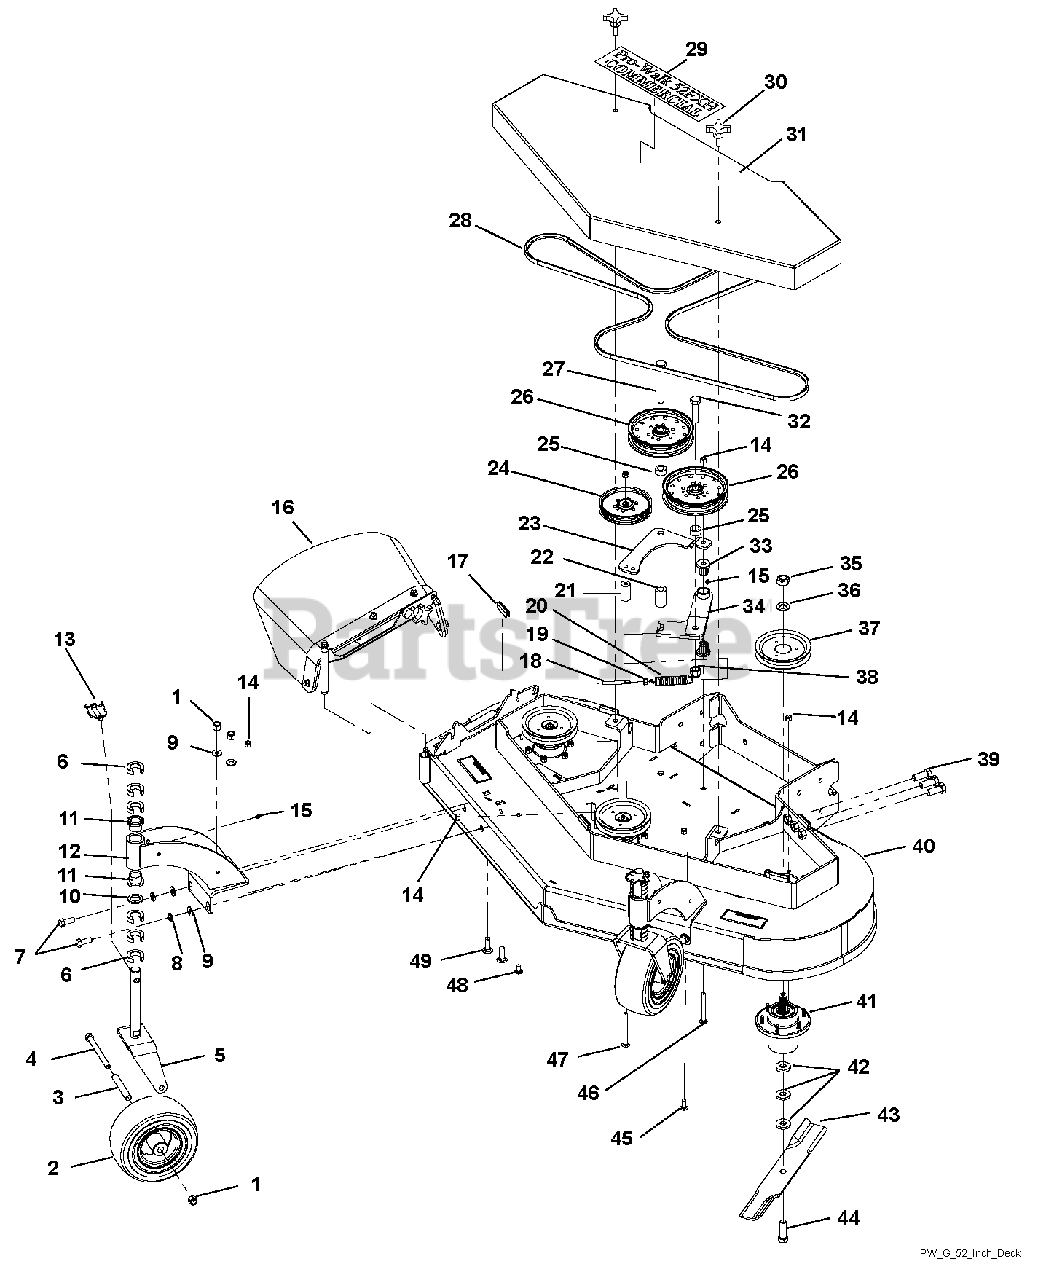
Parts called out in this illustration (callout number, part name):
1	Locknut, .50-13 Nyloc
2	Assembly, Wheel and Tire 9 x 3.5
3	Tube, Caster Axle
4	Bolt, .50-13 x 5.50 Hex Grade 5
5	Weldment, Caster Yoke w/Gravely Paint
6	C-Spacer, 1.00 x 1.77 x .500
7	Bolt, .50-13 x 1.25 Hex 5
8	Washer, Lock .50 x .125 Regular
9	Washer, Flat .50 x 1.25 x .083
10	Bushing, 1.03 x 1.50 x .179
11	Bearing, Flange 1.00 x 1.25 x 1.00
12	Weldment, Strut Front FXWLK w/Gravely Paint
13	Pin, LNC .438 x 2.00
14	Locknut, .38-16 Nyloc
15	Fitting, .25-28 STRGT Grease Zerk
16	Discharge Shield Assembly
17	Trim, 1/4" Trim-LOK
18	Rod, Threaded Adjustment
19	Nut, .375-16 Spring Lock Flanged
20	Spring, Ext .875 x .125 x 4.25
22	Bushing, .688 x 1.13 x 1.89
23	Strap, Idler 52 FXWLK
24	Pulley, Flat 5.00 x .375 w/Bearing
25	Bushing, .688 x 1.13 x .55
26	Pulley, Flat 6.00 x .635 w/Bearing
27	Bolt, .62-11 x 4.50 Hex Grade 5
28	Belt, HB 124.0 Elbow AMD
29	Decal, Pro-Walk Commercial 52 FXH
30	Knob, .375 x 1.25-4 Prong
31	Weldment, 52" Belt Shield Gravely
32	Bolt, Hex .62-11 x 2.50 Grade 5
33	Bearing, Flange M10 x M25 x M27 Fluted
34	Weldment, Idler Arm
35	Locknut, .75-16 Crown
36	Washer, .75 x 1.313 x .113
37	Pulley, Spline Spindle Offset
38	Nut, Lock, Nylon .625-11
39	Bolt, .625-11 x 1.50 Hex Grade 8
40	Assembly, Deck 52 Gravely w/Decals
41	Assembly, Spindle Housing
42	Washer, Blade
43	Blade, 16.500 Lo-Lift
44	Bolt, .62-11 x 2.00 Hex 8
45	Bolt, .38-16 x 1.00 Round Head Square Neck Grade 5
46	Bolt, .38-16 x 3.50 Round Head Square Neck Grade 5
47	Bolt, .38-16 x 4.00 Round Head Square Neck Grade 5
48	Bolt, .38-16 x .75 Round Head Square Neck Grade 5
49	Bolt, .50-13 x 1.50 Round Head Square Neck Grade 5
